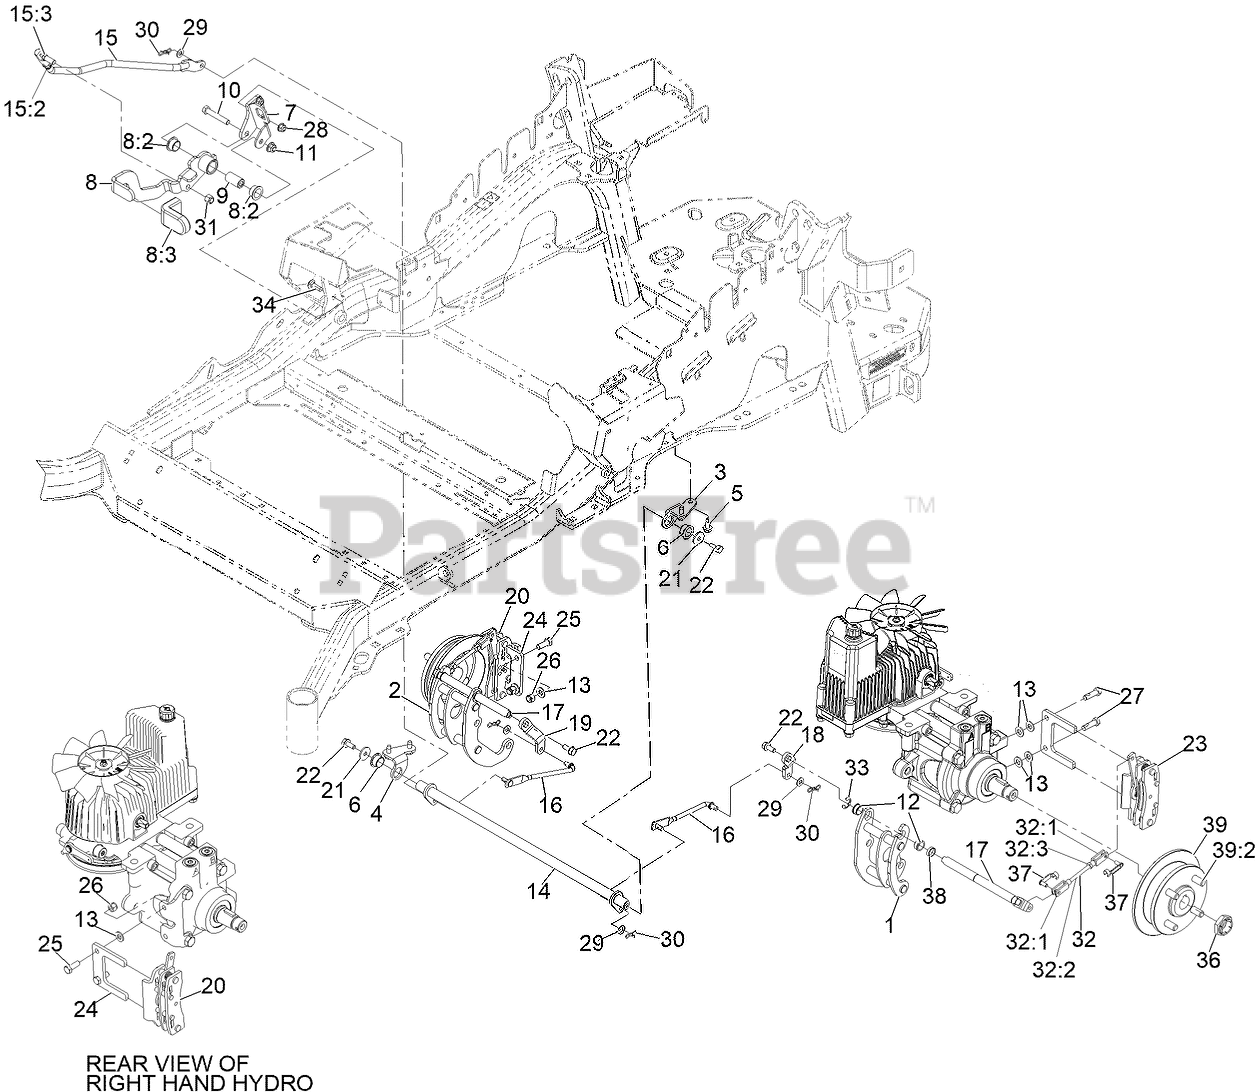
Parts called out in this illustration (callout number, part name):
1	MOUNT-BELLCRANK, LH
2	MOUNT-BELLCRANK, RH
3	MOUNT-PIVOT, LH
4	MOUNT-PIVOT, RH
5	Screw-HWH 5/16-18 X 3/4 Tf
6	BUSHING-FLANGE
7	BRACKET-MOUNT
8	BRAKE LEVER ASM W/GRIP M-R
8:2	BUSHING-FLANGE
8:3	GRIP-LEVER
9	HANDLE-PIVOT, BRAKE
10	SCREW-HH
11	NUT-HF, NI
12	BUSHING
13	WASHER-FLAT
14	Shaft-Cross
15	ASM, Front Linkage
15:2	END-TIE ROD, RH
15:3	NUT-HJ
16	MID-LINK, SHORT
17	BELLCRANK
18	ARM-INNER, LH
19	ARM-INNER, RH
20	Caliper-Brake, RH
21	WASHER-FLAT
22	SCREW-HHF
23	Caliper-Brake, LH
24	PLATE-MOUNT, BRAKE
25	SCREW-HH,
26	NUT-LOCK
27	Screw-HH, Patch
28	NUT-HF, NI
29	WASHER-PLAIN
30	PIN-COTTER, LOCKING
31	NUT-LOCK
32	REAR LINKAGE ASM
32:3	NUT-JAM
34	BOLT-CARR
36	LOCKNUT
37	PIN-CLEVIS, SPRING
39	Wheel Hub ASM
39:2	STUD-WHEEL
